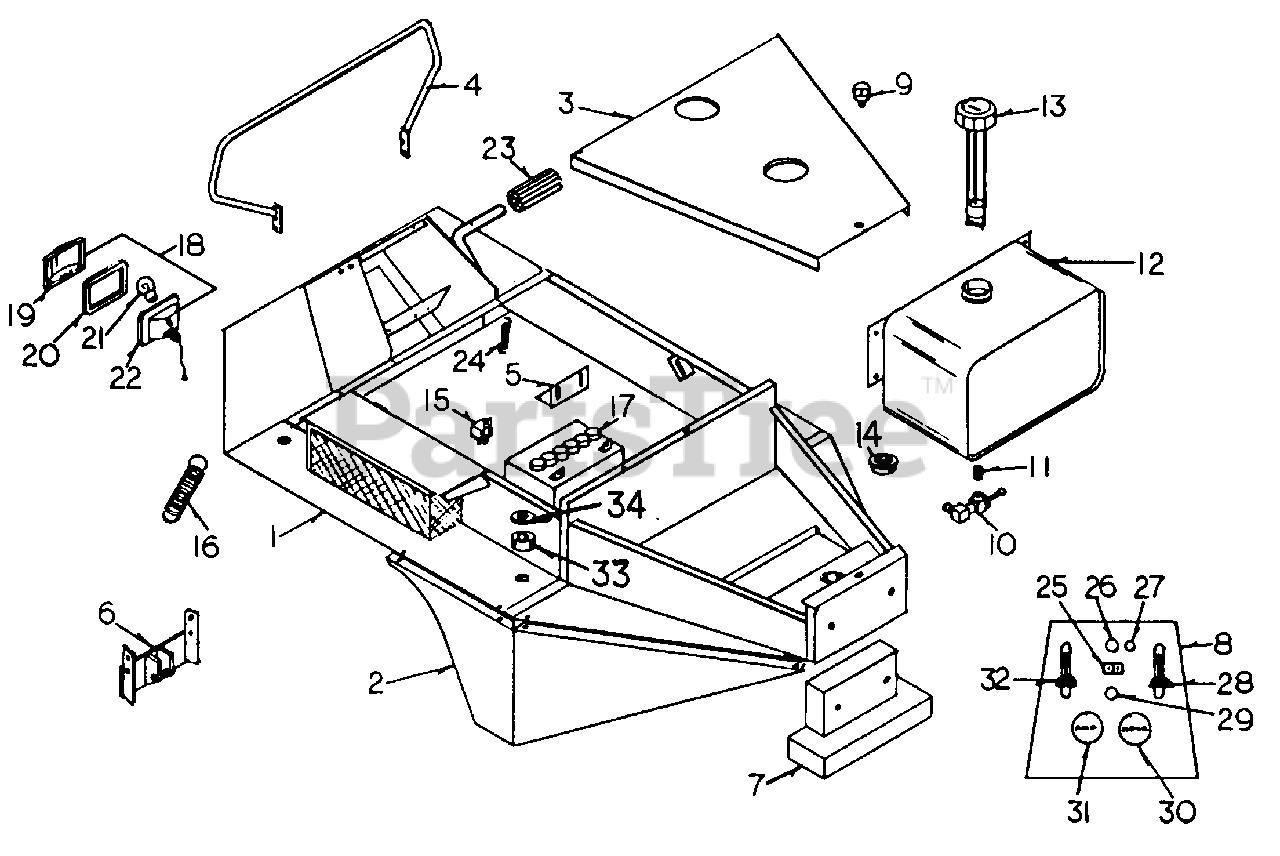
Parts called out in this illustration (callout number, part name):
1	Body
2	Fender, LH
6	Top Cylinder Mount
10	Shut-off Valve
13	Fuel Tank Cap w/Gauge
15	Relay
18	Light Assembly
19	Lens
20	Gasket
21	Bulb
23	Brake Pedal Pad
25	Light Switch
26	Clutch Switch
28	Throttle Cable
29	Ignition Switch
33	Rubber Body Mount
34	Body Mount Washer
